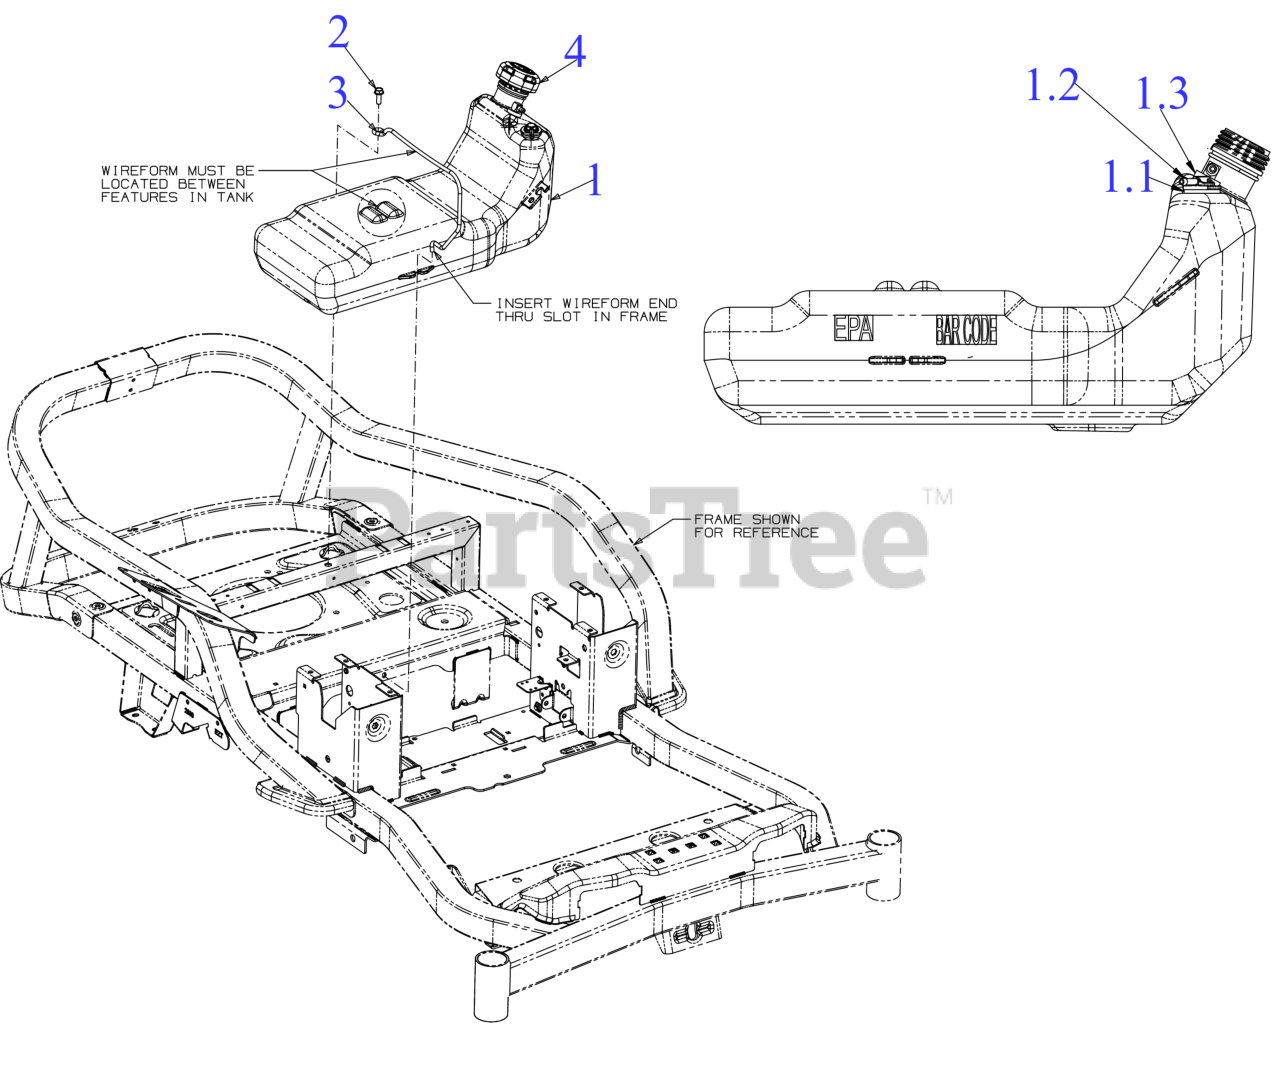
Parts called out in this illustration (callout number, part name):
1	FUEL TANK (3.5 GAL)
1.1	RUBBER GROMMET 23.0 ID x 35.5 OD
1.2	ROLLOVER FUEL VALVE
2	SCREW 5/16-18 x .875 GR5
3	FUEL TANK RETAINER
4	FUEL CAP W/TETHER
